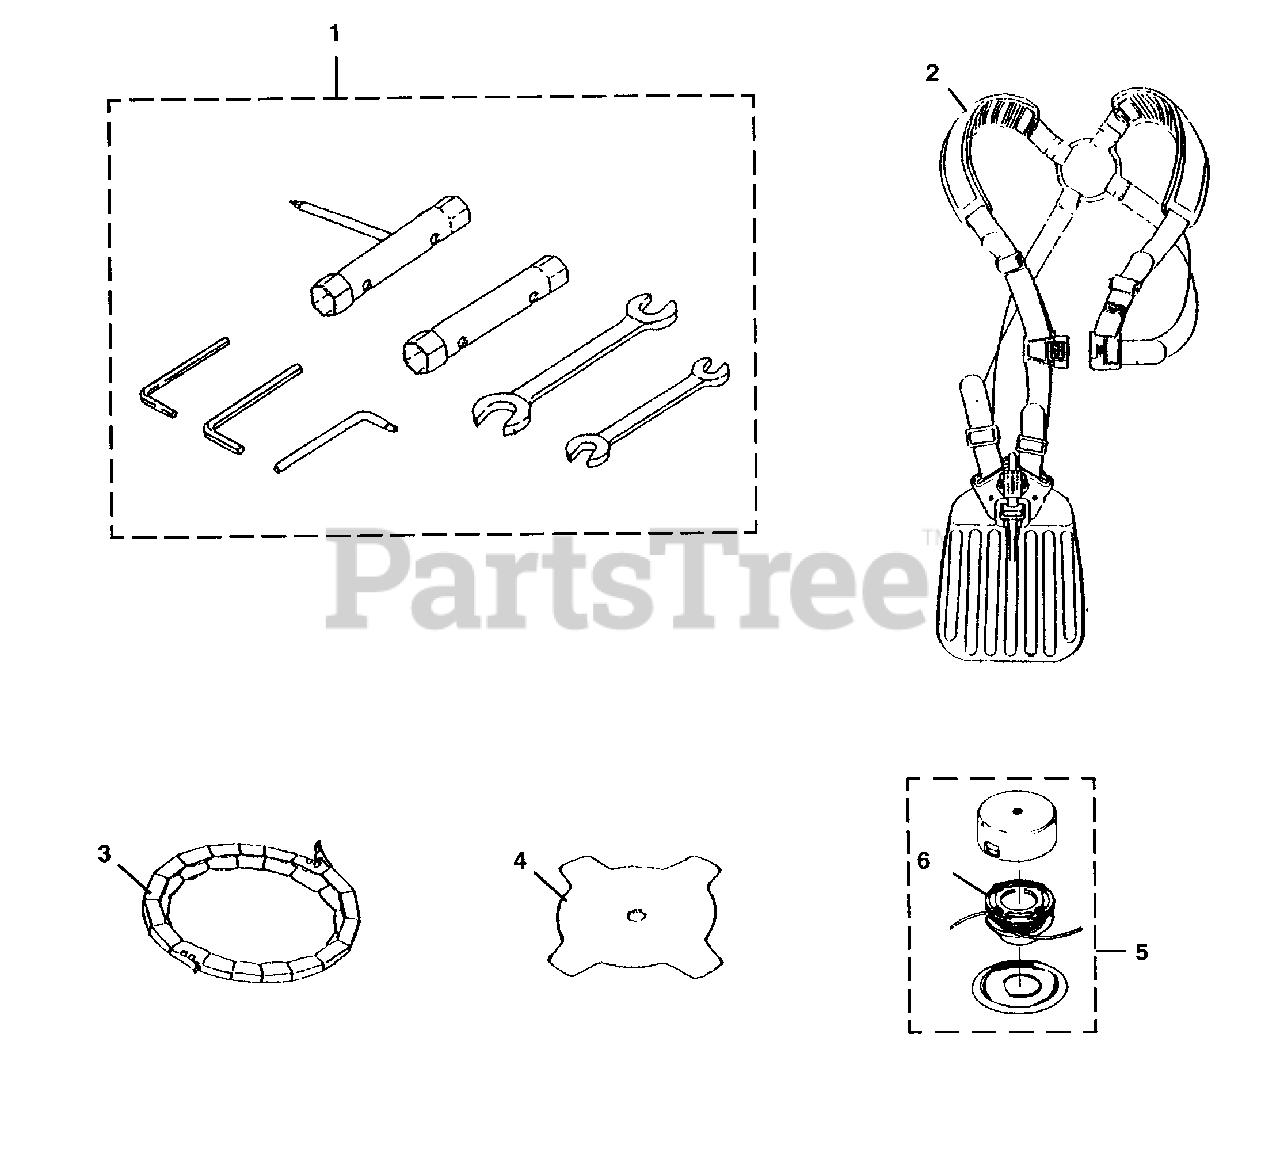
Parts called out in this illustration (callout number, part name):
1	TOOL KIT
3	BLADE COVER
4	BLADE, CUTTER
5	STRING HEAD ASSY
6	SPOOL & STRING
